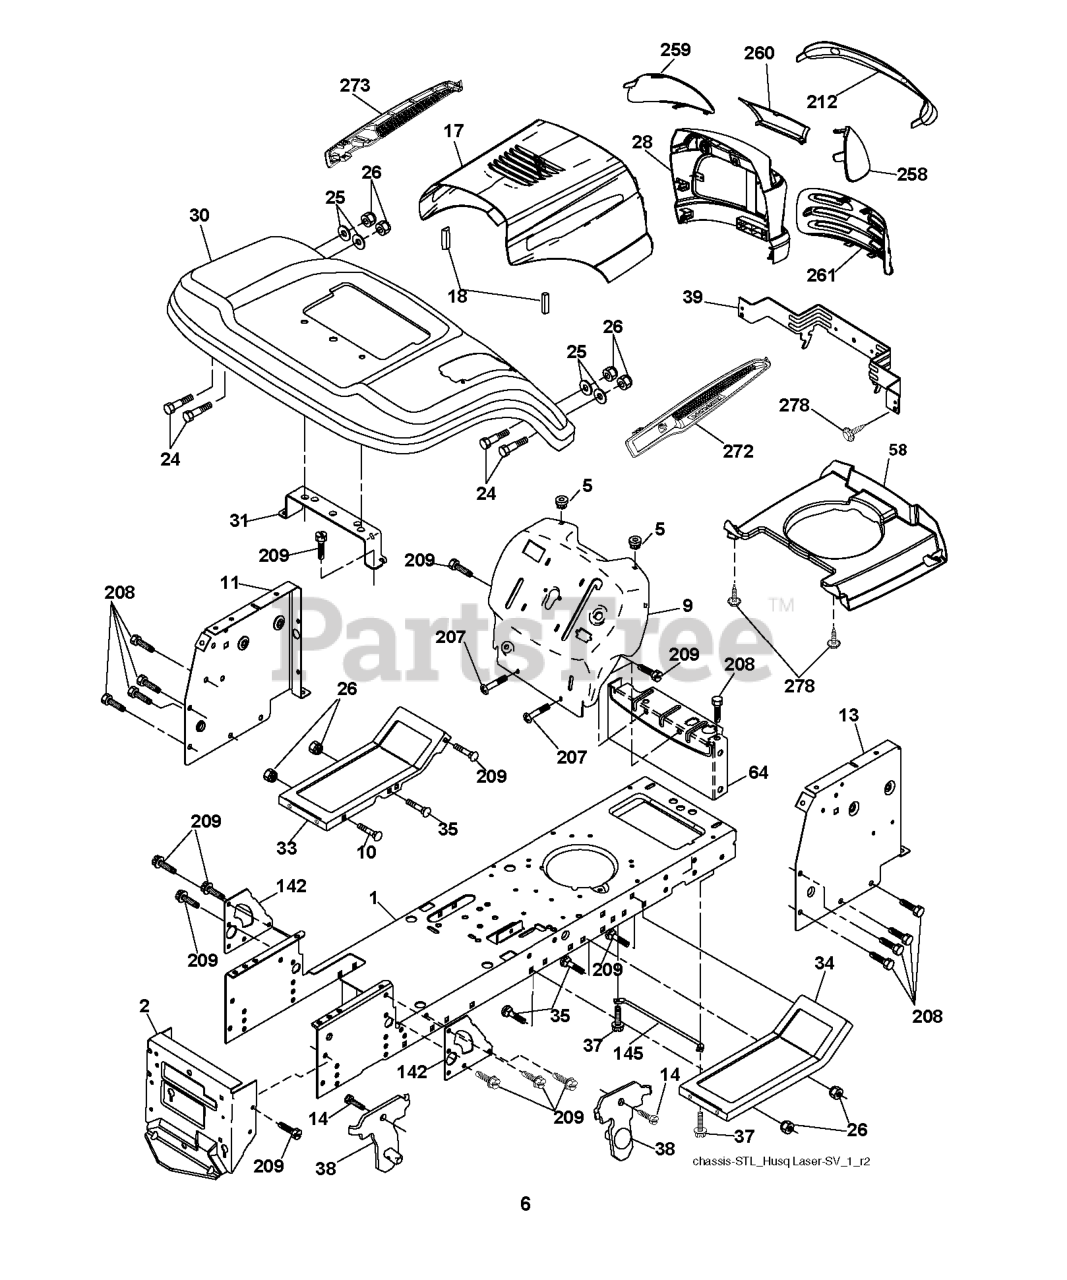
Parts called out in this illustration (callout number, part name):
1	CHASSIS STAMPING
2	DRAWBAR, 12GA
5	BUMPER.RUBBER.HOOD
9	DASH.SLKSCR.SL.PL.C.NA.NHMHUS
10	BOLT D
11	PANEL.DASH.LH.LTX
13	PANEL DASH RH
17	VENT.HOOD.LASER.III
18	BUMPER.HOOD.LARGE.1.75"
25	WASHER
26	NUT
30	FENDER.PNT.LTST.W/S.N/C.668ROS
31	BRACKET FENDER
33	FOOTREST.PNT.LH.BLACK
34	FOOTREST, RH
37	Screw 5/16-18 x 1/2 Hex, Self Tapping 5/16-18 x 1/2
38	BRACKET.ASM.PIVOT.MOWER.REAR
39	BRACKET PIVOT
64	DASH LOWER
142	PLATE REINFORCEMENT
145	ROD.PIVOT.HOOD
207	SCREW, 5/16-18 X 1/2
208	SCREW 3/8-16X1/2
209	SCREW, 3/8-16X3/4
212	INSERT.LENS.REFLECTIVE
258	LENS LH
259	LENS LH
260	COVER.LENS.HUSQ.LASER
272	VENT.HOOD.LASER.
273	VENT.HOOD.LASER.
278	SCREW.#10 X 0.750.BOS
